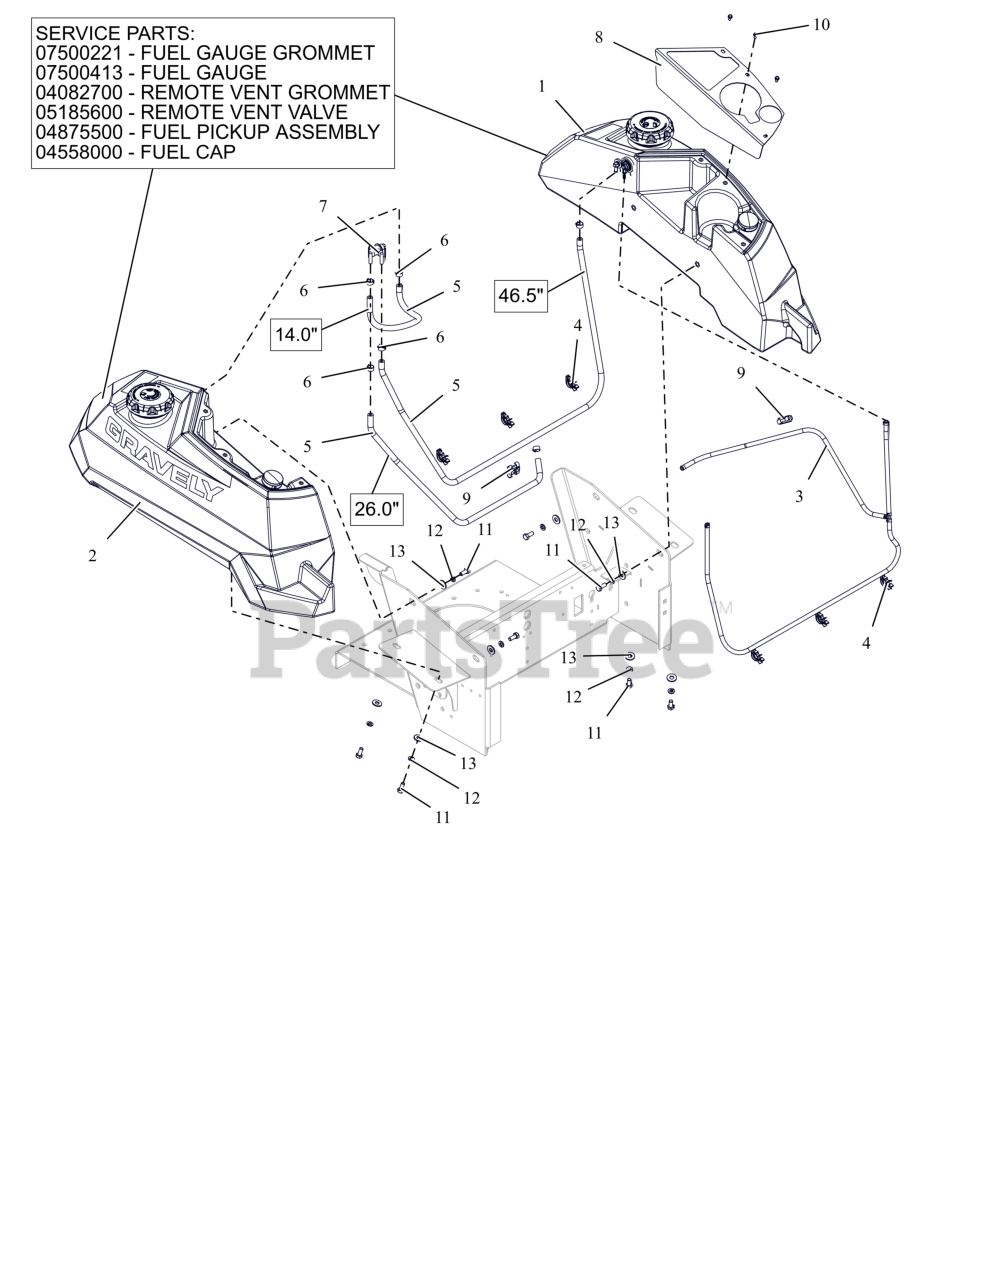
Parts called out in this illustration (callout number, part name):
1	ASM, LH - PT100 FUEL TANK
1	GROMMET, FUEL GAUGE
1	GAUGE, REMOTE SEALED FUEL
1	GROMMET, REMOTE VENT NITRILE
1	VALVE, COMBINATION VENT 3/16
1	ASSM,LRG TANK FUEL PICKUP LINE
1	CAP, FUEL VENTIN AUTOLOCK
2	ASM, RH - PT100 FUEL TANK
2	GROMMET, FUEL GAUGE
2	GAUGE, REMOTE SEALED FUEL
2	GROMMET, REMOTE VENT NITRILE
2	VALVE, COMBINATION VENT 3/16
2	ASSM,LRG TANK FUEL PICKUP LINE
2	CAP, FUEL VENTIN AUTOLOCK
3	ASM, VAPOR LINE
4	WIRE CLIP
5	1 INCH OF HOSE, .25 LOW-PERM BULK GAS
6	CLAMP, FUEL LINE
7	VALVE, FUEL
8	PT100 CUPHOLDER PANEL - RED
9	CLIP, T, .38-.50
10	SCR-MCH 10-24X.38 HWHSTAINLESS
11	BLT,HEX .31-18X.75 G5 ZCC
12	WSHR,LK-REG .312X.078 ZCC
13	WSHR,FLT .375X.875X.083 ZCC
